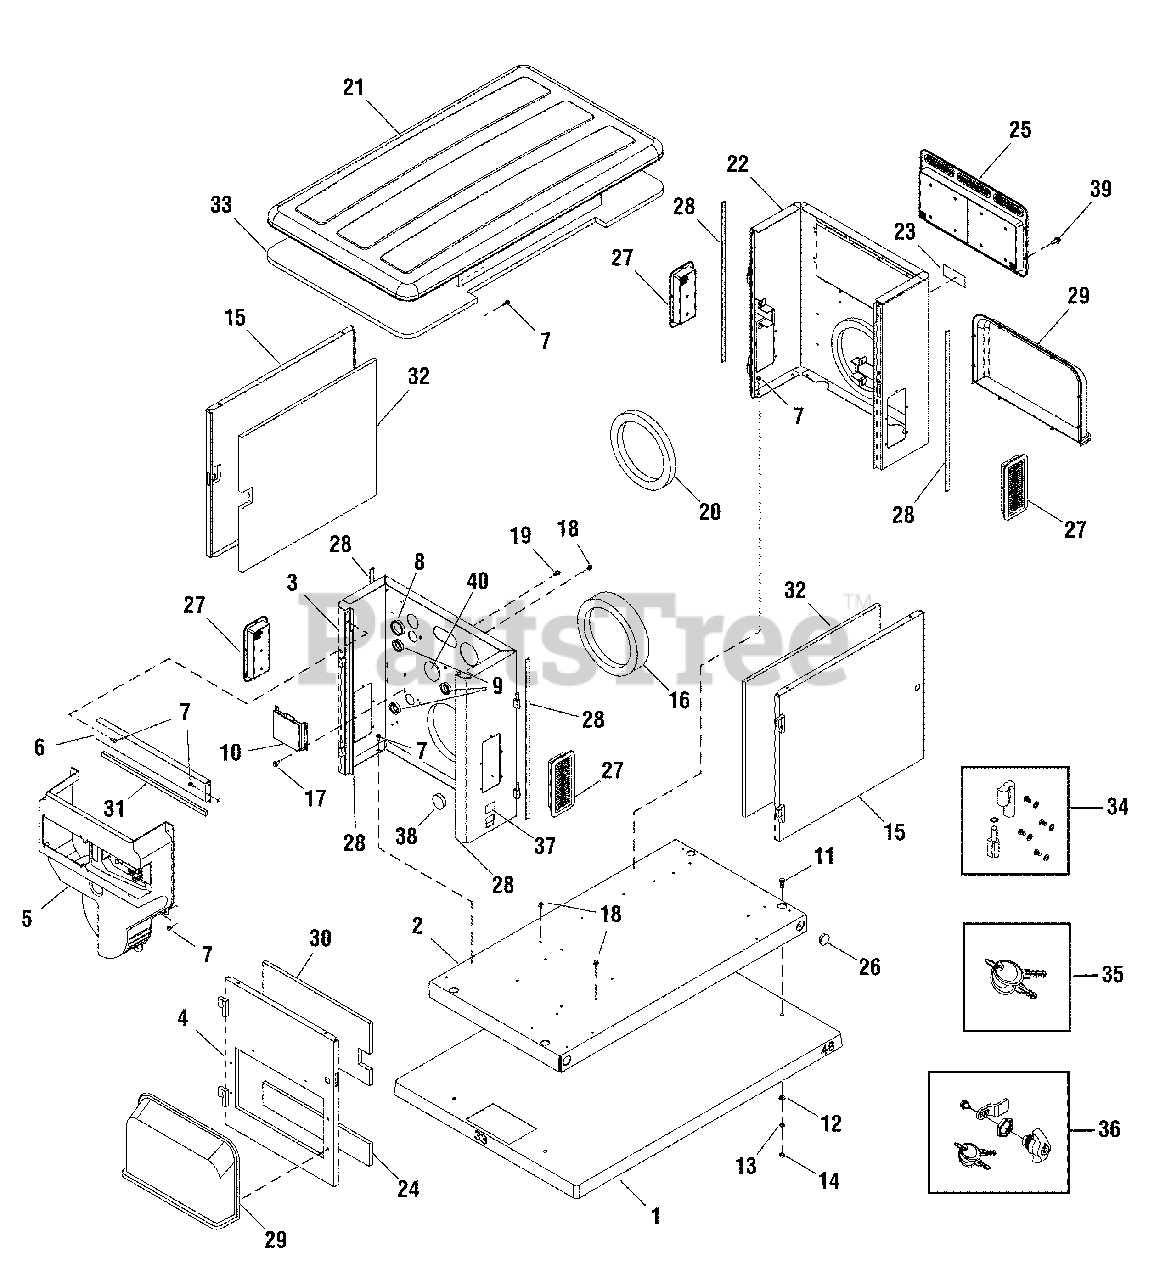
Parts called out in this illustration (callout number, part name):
2	BASE
3	BULKHEAD, Engine
7	BOLT
10	REGULATOR, Voltage
11	* CAPSCREW, Hex Head, 3/8-16 x 1
12	* WASHER, Flat, 3/8-M10
13	* WASHER, Lock, 3/8
14	* NUT, 3/8-16
16	SEAL, Foam
20	SEAL, Foam
22	BULKHEAD, Alternator
29	COVER, Air Intake
37	DECAL
39	SCREW
